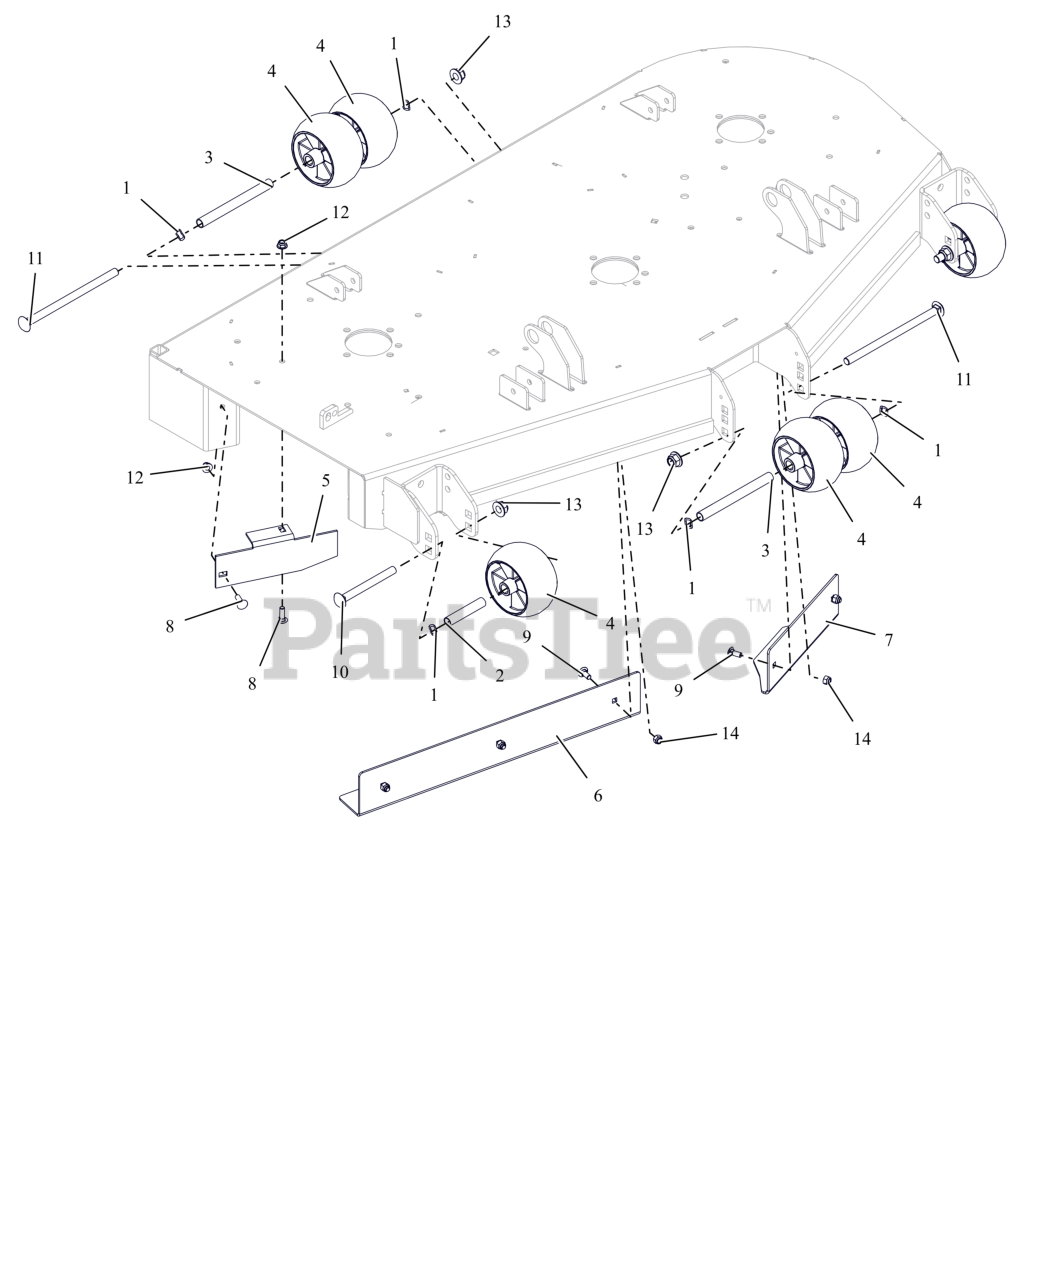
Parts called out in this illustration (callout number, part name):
1	WAVE WASHER .531X.781X.125FH
2	SPACER, .510X.625X3.35
3	SPACER, .510X.625X6.50
4	ANTI-SCALP WHEEL - 5X3 CTR
5	BAFFLE, DISCHARGE, 52"
6	BAFFLE, 52" RH VACUUM (ORANGE)
7	BAFFLE, 52" LH VACUUM (ORANGE)
8	BLT,RHSN .31-18X1.00 G5 ZCC
9	BLT,RHSN .31-18X.75 G5 ZCC
10	BLT, RHSN .50-13X5.00 G5 ZCC
11	BLT, RHSN .50-13X8.50 G5 ZCC
12	NUT,LK-NYL-FLG .31-18 G5ZC120
13	NUT,NYL-FLG .50-13 GF ZCC
14	NUT,NYL .31-18 G5 ZCC
